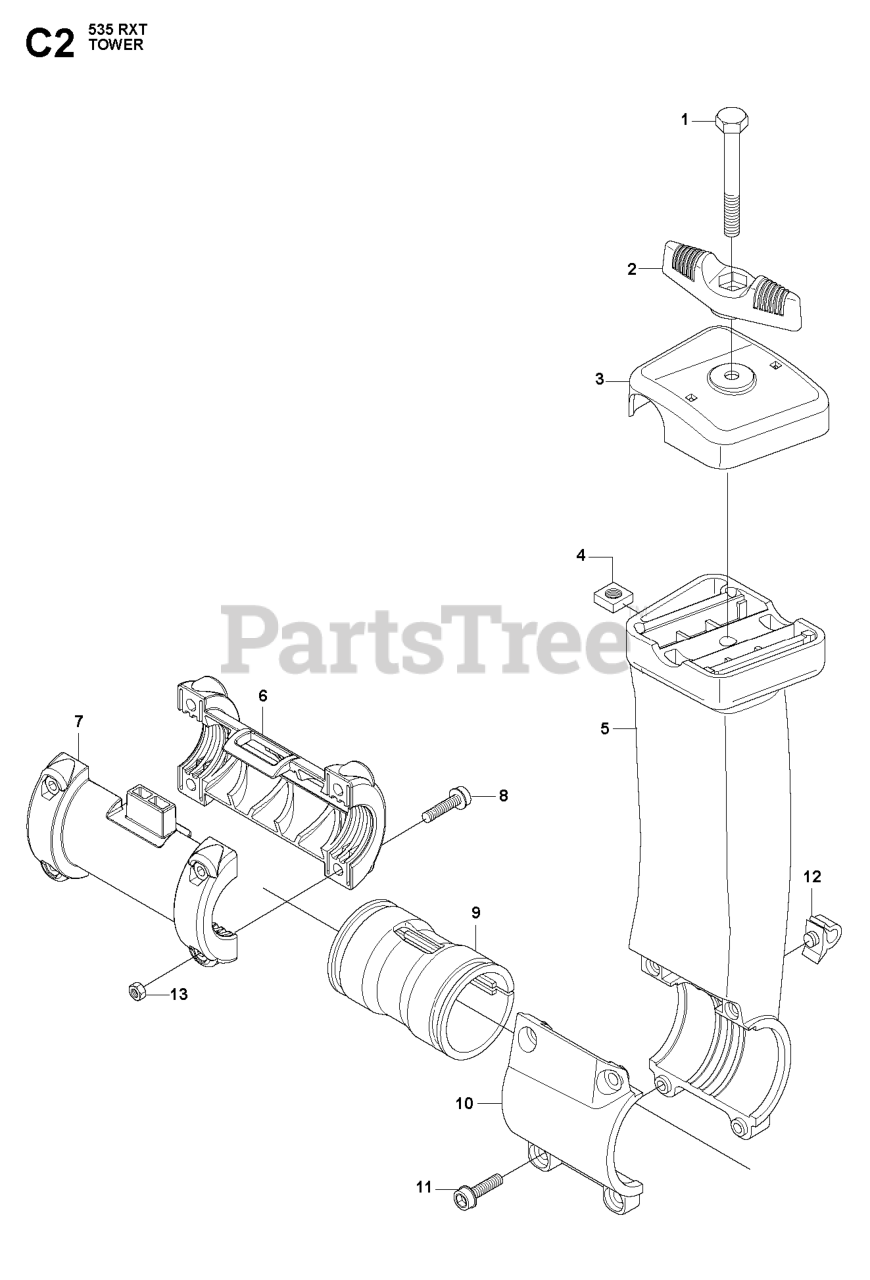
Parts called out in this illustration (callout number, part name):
1	%SCREW
3	PROTECTOR CLAMP
5	BRACKET
6	CLAMPING SLEEVE
7	CLAMPING SLEEVE ASSY
9	VIBRATIONS ABSORBER
10	COVER, BRACKET
